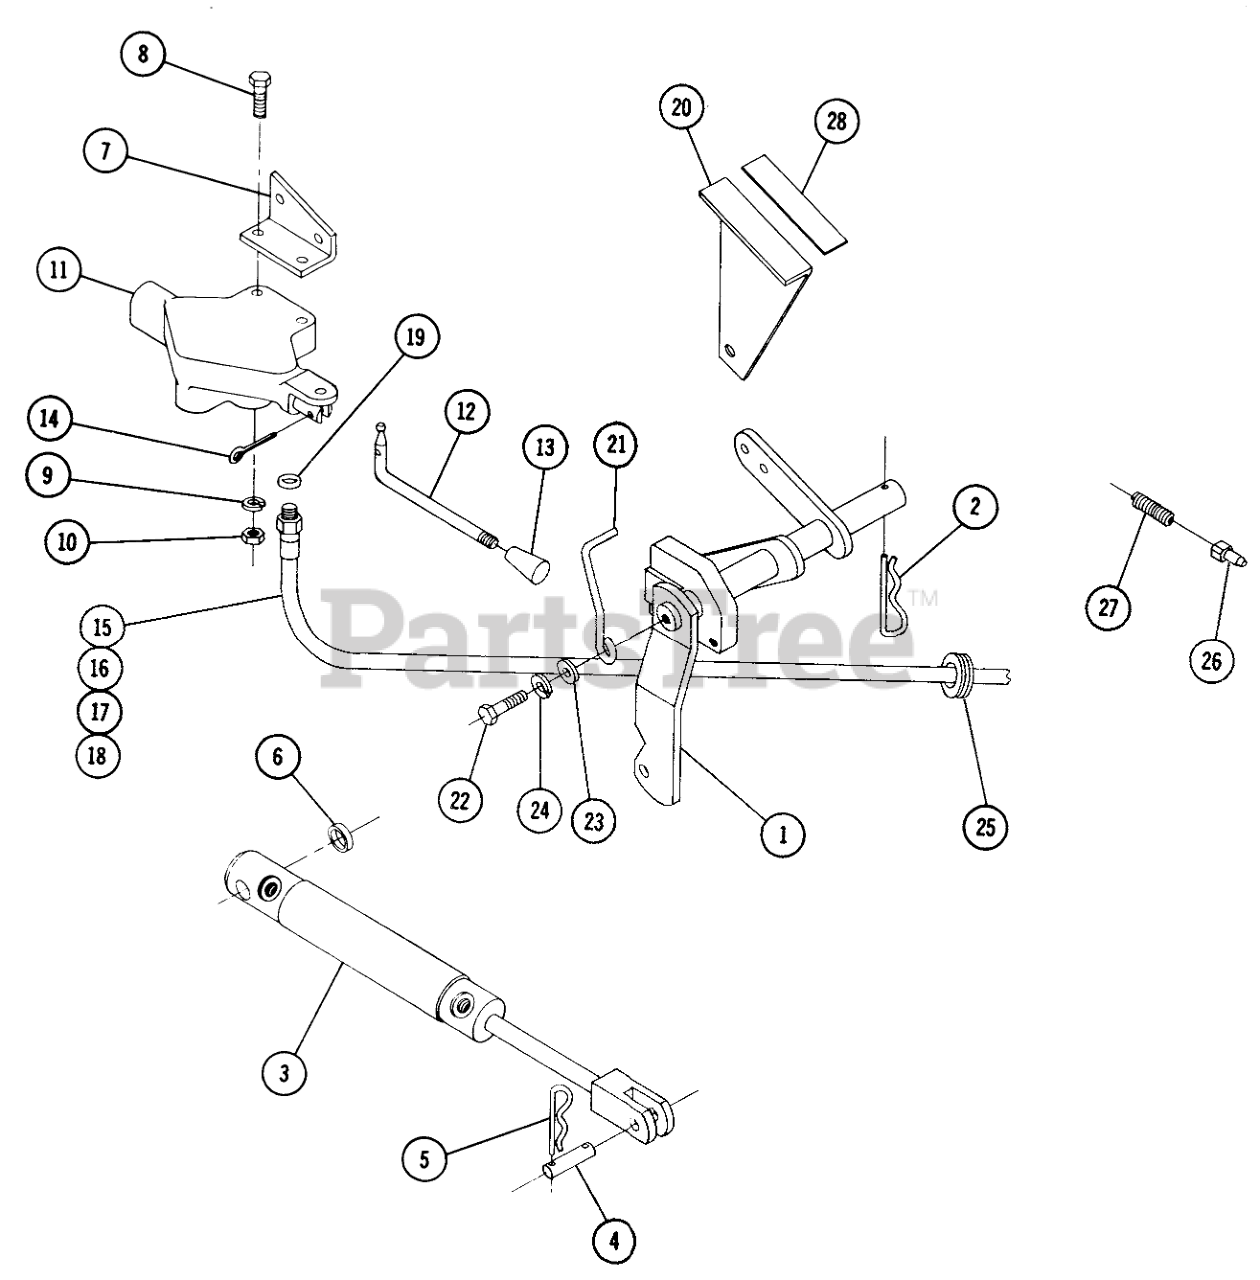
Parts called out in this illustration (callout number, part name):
1	Lift Arm
2	Hairpin
3	Cylinder
4	PIN
5	Hairpin
6	Spacer
7	SUPPORT-VALVE
8	Bolt 1/4 20 x 1 1/4
9	Lockwasher
10	Nut-Nylok
11	Valve
12	VALVE LEVER
13	Knob
14	Cotter Pin
15	Ass-y. Hose-29"
16	Ass-y. Hose-20"
17	Ass-y. Hose-14-1/2"
18	Hose-111/2
19	"O" Ring
20	Indicator Plate
21	Arm
22	Bolt 5/16-18 x
23	Washer
24	Lockwasher
25	Grommet
26	Cone
27	Spring
28	Decal
